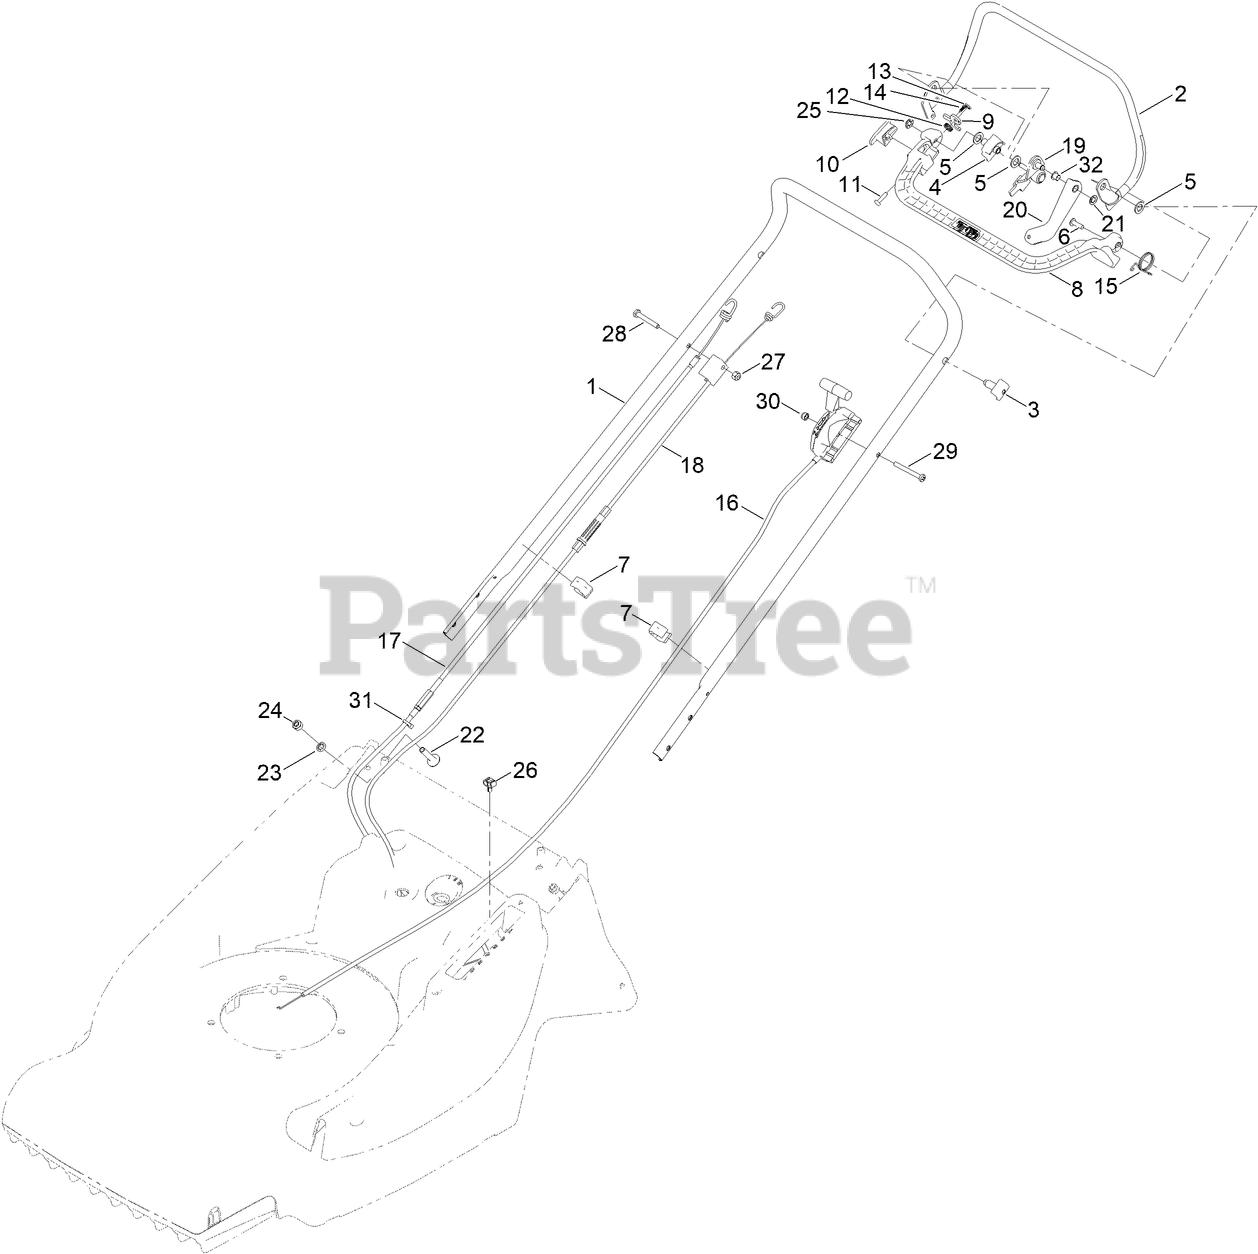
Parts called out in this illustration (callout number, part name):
1	HANDLEBAR-UPPER
2	LEVER-CLUTCH, GEARBOX
3	PIN-PIVOT
4	CLAMP-BAR
5	WASHER-NYLON
6	SCREW
7	GUIDE-CABLE
8	ARM-BAIL
9	LEVER-CATCH
10	LATCH-BUTTON
11	LATCH-PIN
12	LEVER-BAIL, SPRING
13	FASTENER-STARLOCK, PUSH-ON
14	CLIP-TREE
15	LEVER-BAIL ARM, SPRING
16	THROTTLE-CONTROL
17	CABLE, BBC
18	CLUTCH-CABLE, 3 SPEED
19	ANCHOR PLATE WELDED
20	BBC LINKAGE ASSEMBLY
21	WASHER-STARLOCK
22	BOLT-COACH
23	GRIP-FIX
24	NUT-HEX, NI
25	STARLOCK-DOMED
26	CLIP-CONDUIT, TWIN
27	NUT-HEX
28	BOLT
29	SETSCREW
30	NUT-NYLOC
31	TIE-CABLE
32	BUSH, IGUS (8 X 9 X 8)
